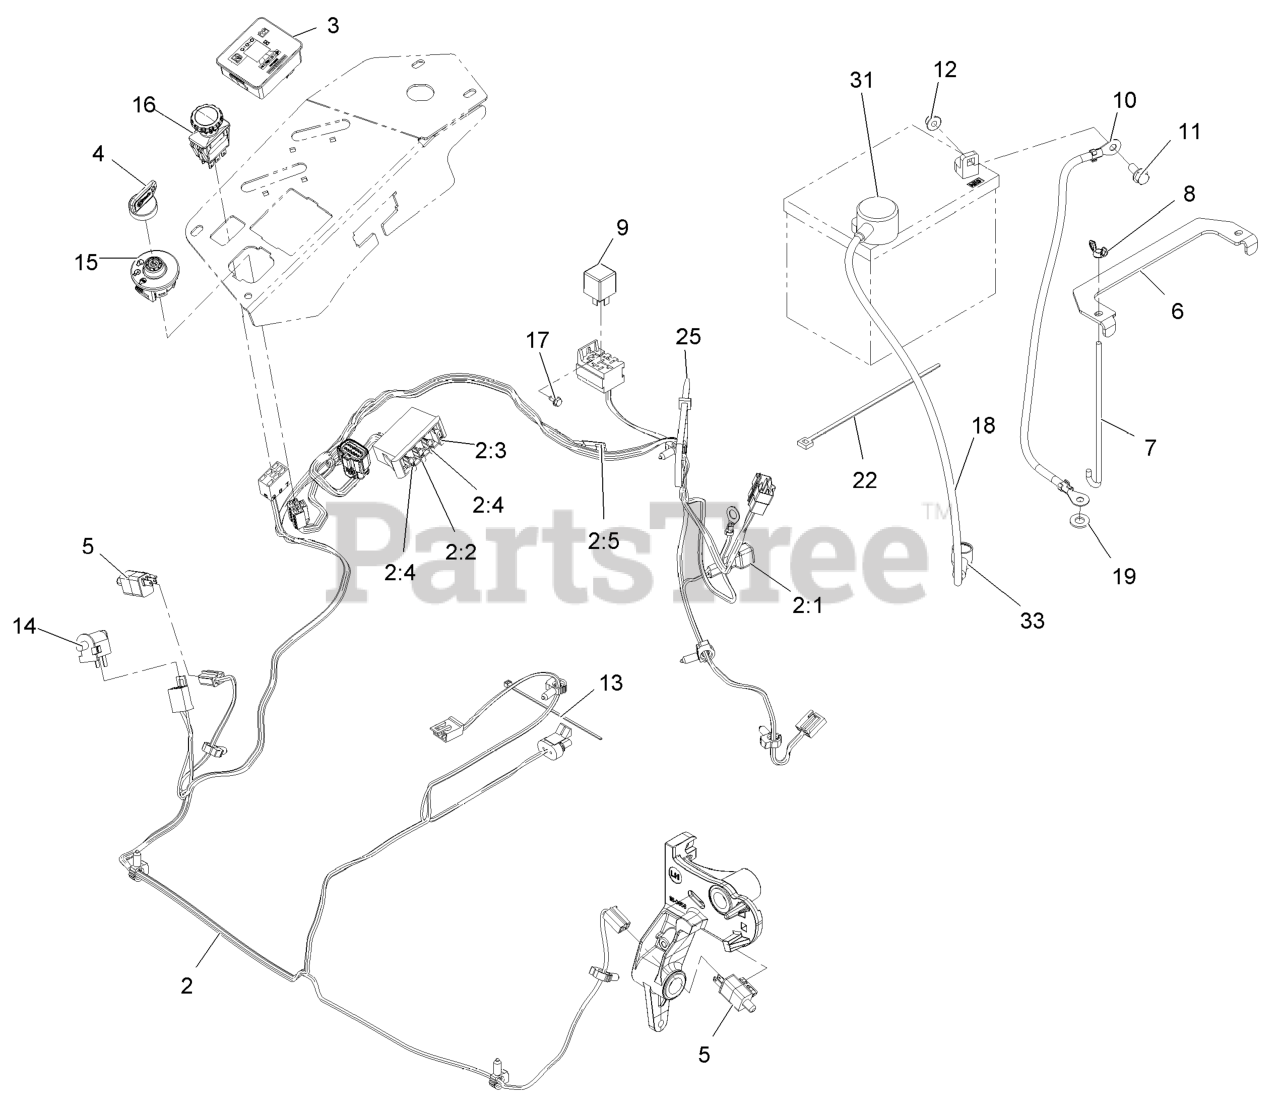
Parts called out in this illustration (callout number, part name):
2:2	FUSE-BLADE, 10 AMP
2:3	FUSE-BLADE, 15 AMP
2:4	FUSE-BLADE, 25 AMP
2:5	CAP-PLUG
3	FUEL/HOUR METER ASM
4	KEYS-IGNITION (SPARE PAIR
4	KEY-IGNITION
6	STRAP-TIE DOWN, BATTERY
7	BOLT-HOLDDOWN
8	WINGNUT
10	CABLE-BATTERY, NEGATIVE
11	SCREW-HHF
12	NUT-HF, NI
13	TIE-CABLE
14	SWITCH-BAIL
16	SWITCH-PTO, 10 AMP
17	SCREW-HWH
18	CABLE-BATTERY, POSITIVE
19	WASHER-FLAT
22	TIE-PLASTIC
25	TIE-PLASTIC
31	INSULATOR-BATTERY
33	INSULATOR-SOLENOID
